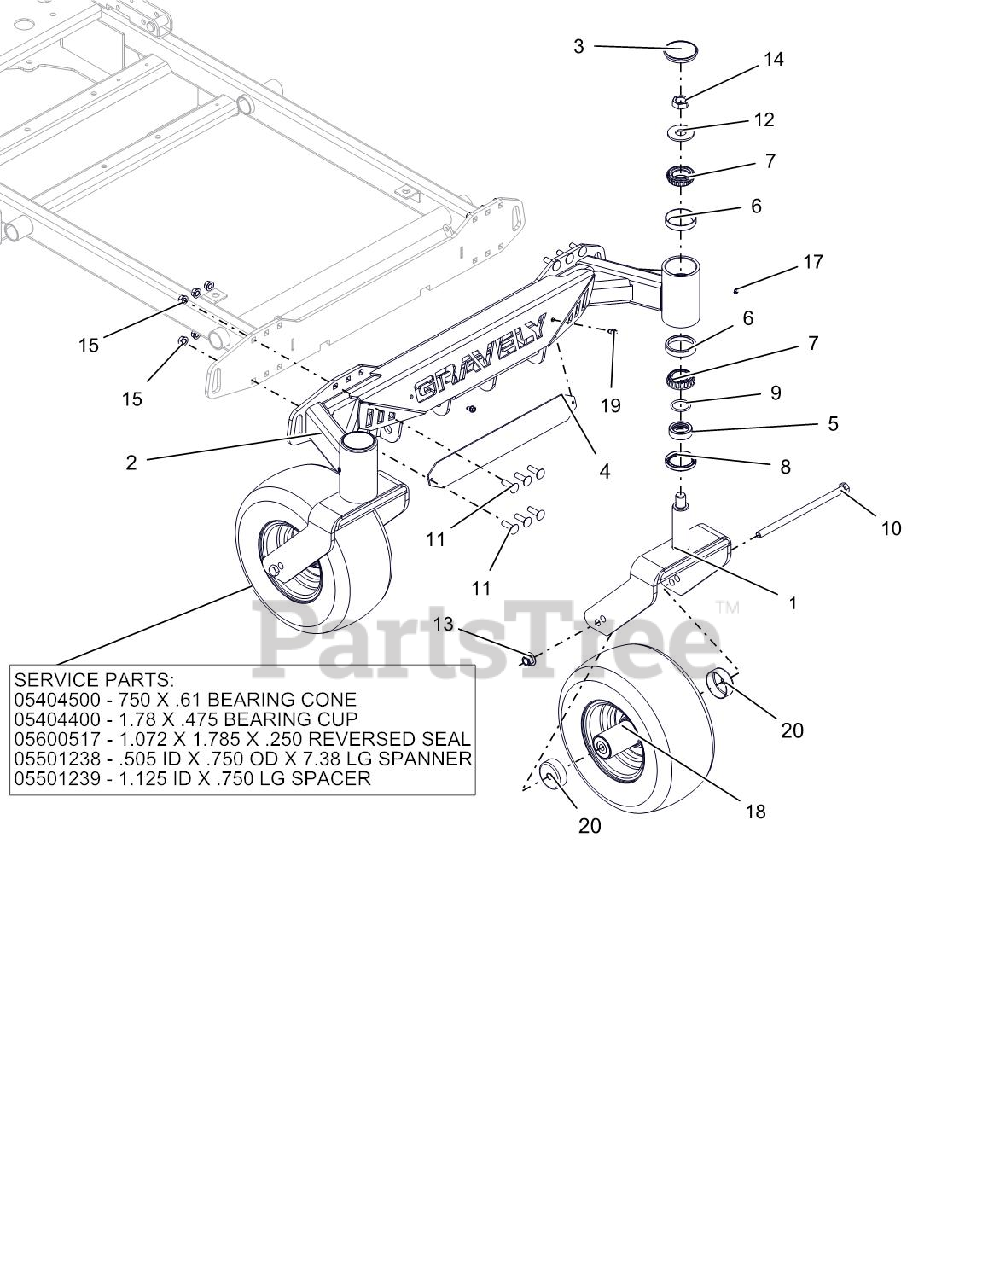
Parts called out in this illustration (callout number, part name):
1	CASTER FORK WMT - RED
2	WMT, 48 FRONT AXLE
3	CAP, DUST
4	BACKER, NAMEPLATE
5	SPACER, FRONT CASTER FORK
6	BRG-CUP 2.328X.465
7	BRG-CONE 1.25X.66
8	SEAL, OIL 1.75 X 2.332 X .312
10	@BLT-HEX .50-13X9.00 GR5 YWZC
11	@BLT-RDHDSQNK .38-16X1.25 G5YZ
12	@WSHR-FL-STL.812X2.00X.148YWZC
13	@NUT-LK-NYL-FLG .50-13 YWZC
14	NUT-JAM TOPLK .75-16 YWZC
15	@NUT-LK-TOP-FLG .38-16 YWZC
17	FTG, .25-28 FLUSH MNT GREASE
18	ASM, WHL/TIRE 13X6.50-6 SEMI
19	SCR-TAP .25-20X.50 HWH TR YWZ
20	SHIELD, WHEEL BEARING
21	BRG-CONE .750X.61
22	BRG-CUP 1.781X.475
23	SEAL, 1.125 X 1.781 X .469
24	SPANNER,.505ID X.750OD X7.38LG
25	SPACER, 1.125 ID X .750 LG
